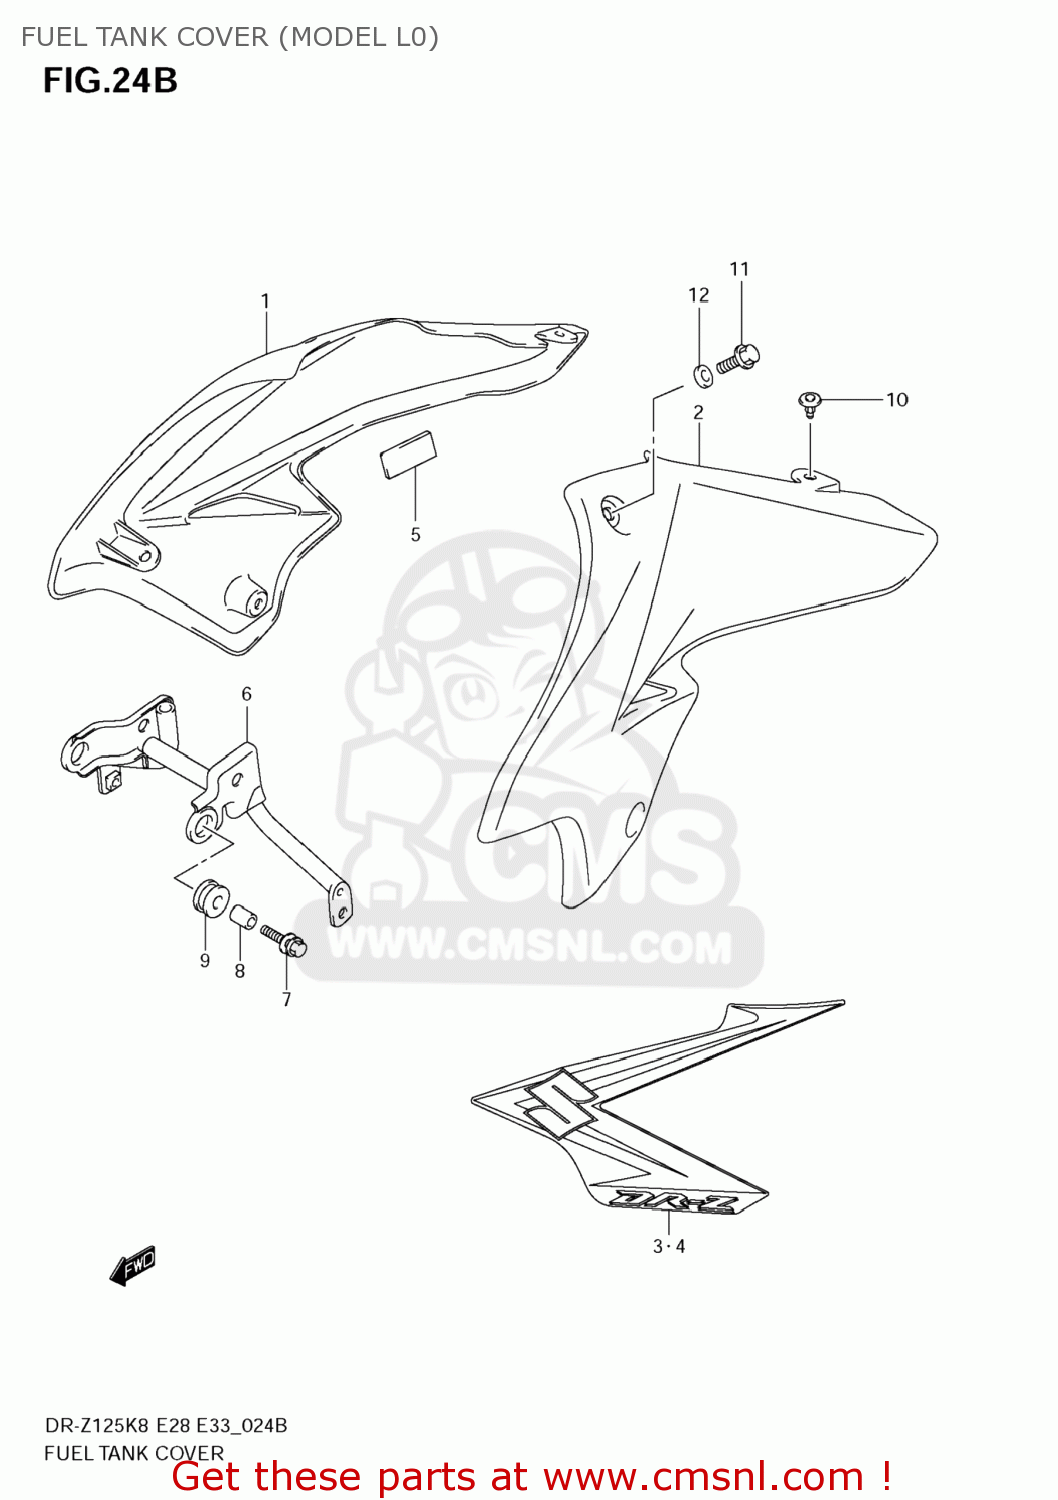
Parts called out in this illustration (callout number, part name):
1	COVER,FUEL TANK,R
2	COVER,FUEL TANK,L
3	TAPE SET,FUEL TANK COVER,R
4	TAPE SET,FUEL TANK COVER,L
5	CUSHION,FUEL TANK COVER
6	BRACKET,FUEL TANK FR
7	BOLT(6X25)
8	SPACER(6.5X9X13.5)
9	CUSHION,FUEL TANK SIDE
10	CLIP(BLACK)
11	BOLT
12	WASHER
